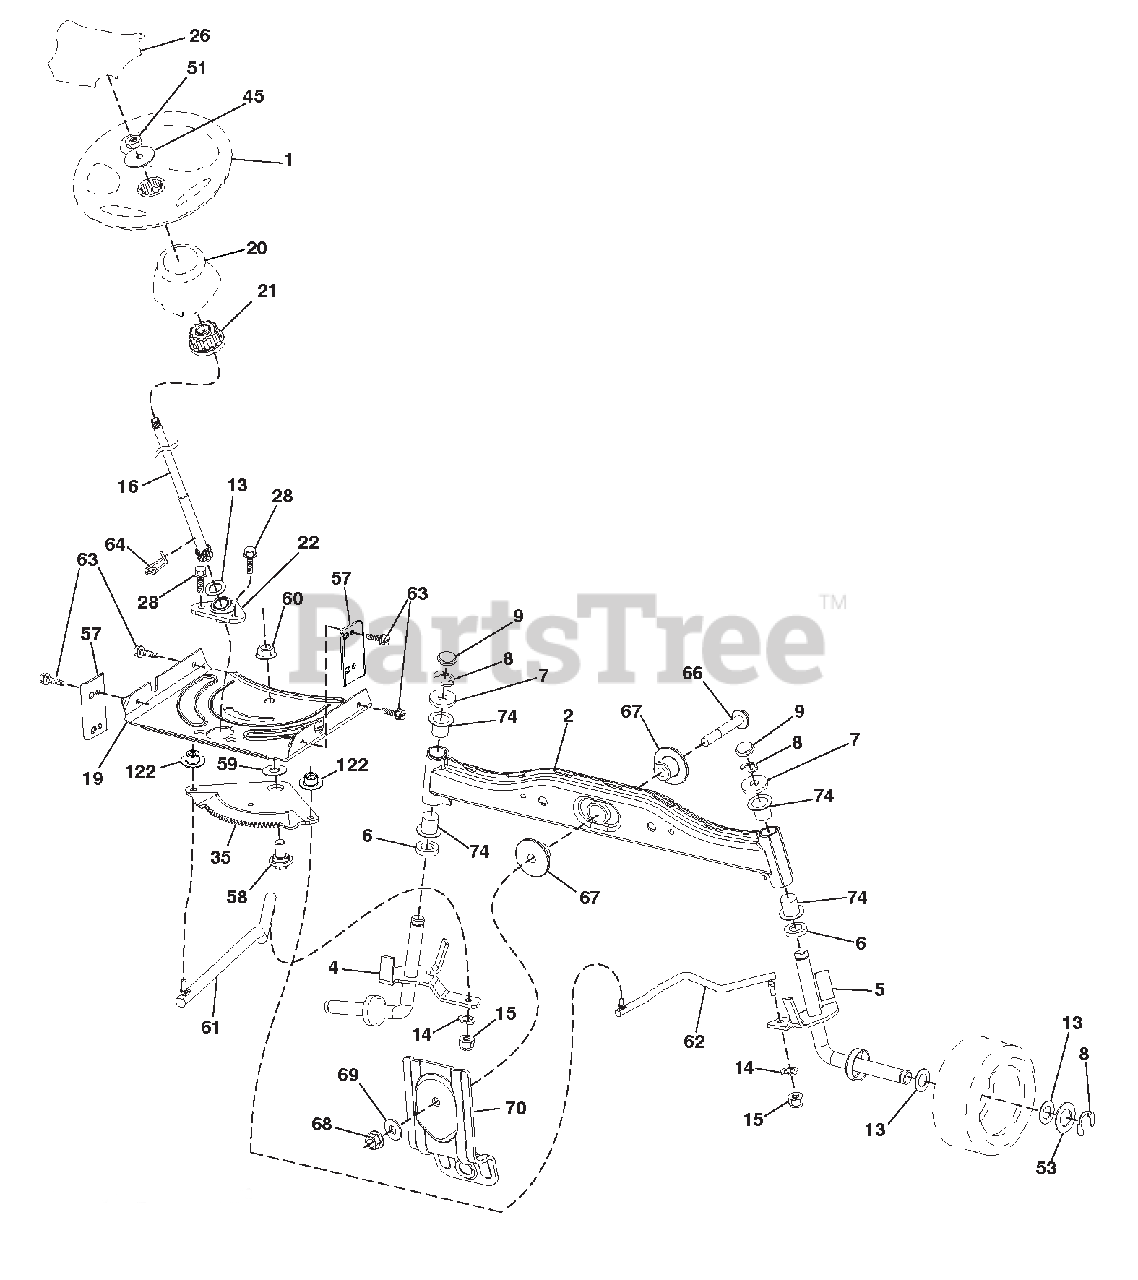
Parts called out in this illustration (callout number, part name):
1	WHEEL STEERING
2	AXLE ASM.WELDED
4	SPINDLE.WELDED.LH.15"TEX
5	SPINDLE.WELDED.RH.15"TEX
6	WAHSER THRUST .75 X 1.230
7	WASHER.25/32 X 1-5/8 X 16GA.
8	RING.KLIP.#T5304-75
9	CAP.SPINDLE.FR.TOP.BLK.
13	WASHER.25/32 X 1 1/4 X 16 GA.
14	Washer, Lock 3/8
15	NUT.CROWNLOCK.3/8-24
16	SHAFT.STEER.3/4 TEX.NON-PLATED
19	PLATE.STEER.DDL.NLT/NGT
20	BOOT STEERING LT TEX P/L .428
21	ADAPTER.WHEEL.STRG..760
22	STEERING SUPT. LOWER
26	CAP WHEEL STEERING HRS/SRS BLK
28	SCREW.HEXWSH THDR3/8-16X3/4.BL
35	GEAR SECTOR.PLATE.DDL.NLT/NGT
45	WASHER.9/16ID X 2-3/8OD.12GZIN
51	NUT.HEX.JAM.TOPLOCK.1/2-20 UNF
53	WASHER.HARDEN..793 X 1.637X060
57	BRACKET.UPSTOP.TEX
58	BOLT.SHOULDER.SECTOR.PIVOT.CFM
59	WASHER.THRUST.SECTOR.STEER.NLT
60	NUT.FLANGE LOCK.5/8-11
61	DRAGLINK.LH.BALLSTUD.DDL.
62	DRAGLINK.RH.BALLSTUD.DDL
63	SCREW.5/16-18X3/4.SMGML.TAP/BL
64	RETAINER.CLIP.SPRING.STEERING
66	BOLT.HEX.FGHD.7/16-14 X 3.SERR
67	BUSHING.PM.FRONT AXLE
68	NUT.LOCK.FLANGE.7/16-14.GR5
69	WASHER.1.5 X .505 X .118
70	BRACKET.DECK.SUSPENSION.FRONT
74	BEARING COL STRNG BLK
122	CAP GEAR SECTOR
